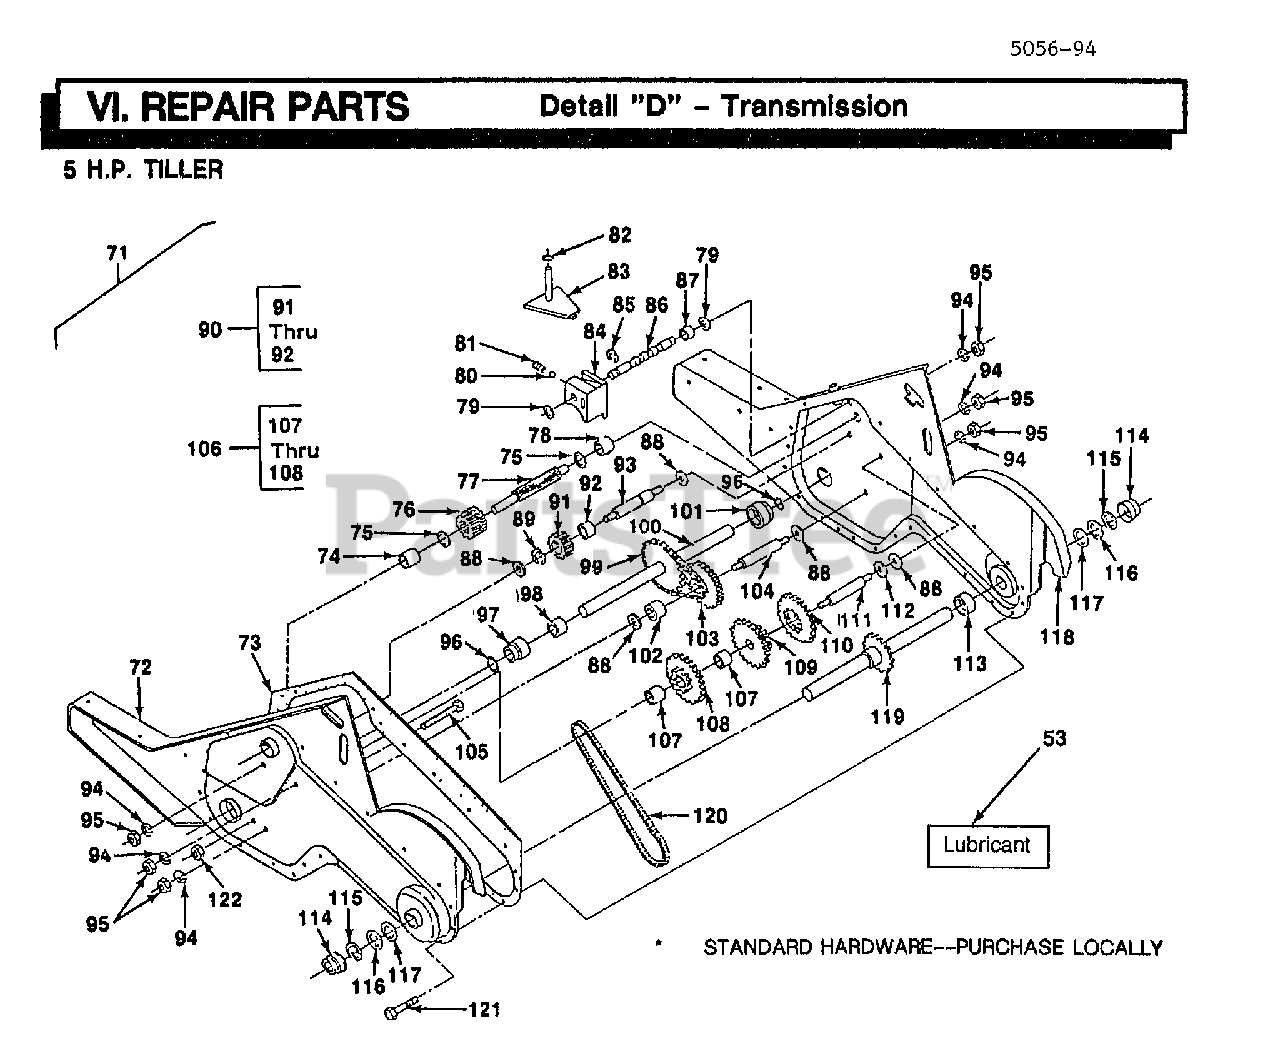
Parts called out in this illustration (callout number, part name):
53	GREASE PREMIUM-1
73	GASKET TI
74	NEEDLE BRNG LT
75	"T, BEARING"
76	PINION-INPUT CRT
77	SHAFT-INPUT CRT
78	"TI, BEARING"
79	WASHER SEAL CRT
81	SPRING-SHIFT CRT
82	O-RING TI
83	ARM ASSY CRT
84	SHIFT FORK TI
85	KLIP RING
86	SHAFT SHIFT CRT
87	SPACER SPLIT CRT
88	WASHER
89	KLIP RING
90	GEAR ASSY CRT
91	GEAR-REV IDLR CRT
92	NEEDLE BEARING TI
93	SHAFT CRT
94	LOCKWASHER
95	NUT.ASF.HEX.7/16
96	O RING CRT
97	"CRT, BEARING"
98	BUSHING TI
99	CHAIN CRT
102	SPACER TI
103	SPRCKT 8 GEAR CRT
104	SHFT 2ND RED. CRT
105	SCRW WHIZ LOK CRT
107	BEARING
109	GEAR TI
110	GEAR TI
111	REDUCTION SHFT TI
112	BRNG RACE
113	SPACER TI
114	CUP.FORMED.
115	RING SPIRAL CRT
119	SHAFT ASSY TI
120	CHAIN.50 LINK TI
121	SCREW CRT
122	NUT.HEX.5/16-18
